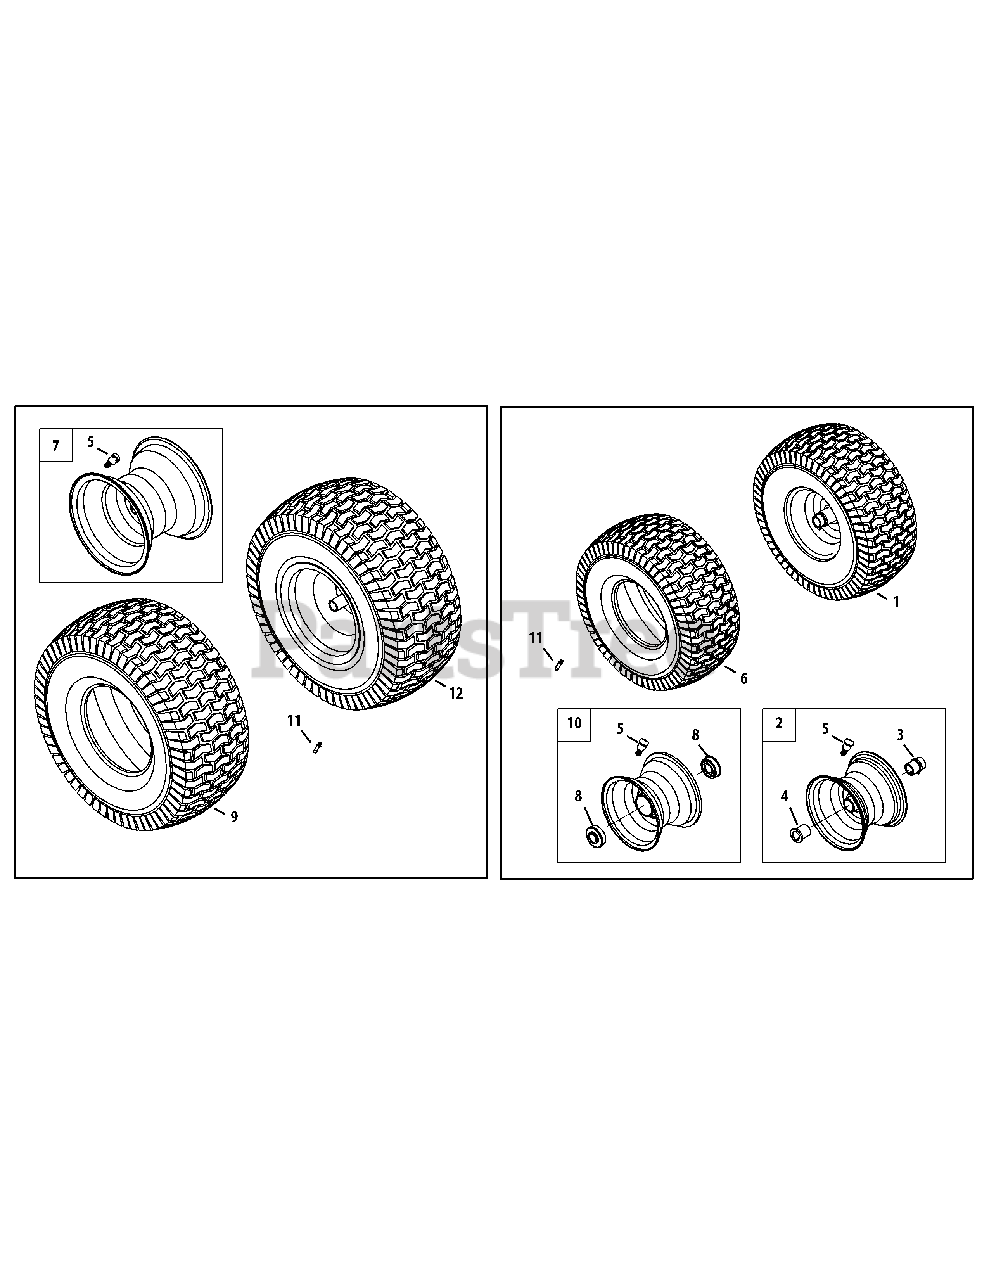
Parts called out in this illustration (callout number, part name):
1	Wheel Ass’y, 15 x 6 Plst. Brg. (Grey)
1	Wheel Ass’y, 15 x 6 Plst. Brg. (Beige)
1	Wheel Ass’y, 15 x 6 Ball Brg. (Grey)
2	Rim Ass'y, Plst. Brg. (Yellow)
2	Rim Ass'y, Plst. Brg. (Grey)
2	Rim Ass'y, Plst. Brg. (Beige)
3	Flg. Bearing .760 ID w/fitting
4	Flg. Bearing .760 x 1.0 x 1.20
7	Rim Ass'y, 8.0 x 7.0 x .750 (Grey)
7	Rim Ass'y, 8.0 x 7.0 x .750 (Yellow)
8	Ball Bearing .750 ID x 1.750 OD
10	Rim Ass'y, Ball Brg. (Beige)
10	Rim Ass'y, Ball Brg. (Yellow)
11	Grease Fit ting
12	Wheel Ass'y, 20 x 8 (Grey)
12	Wheel Ass'y, 20 x 8 (Beige)
12	Wheel Ass'y, 20 x 8 (Yellow)
